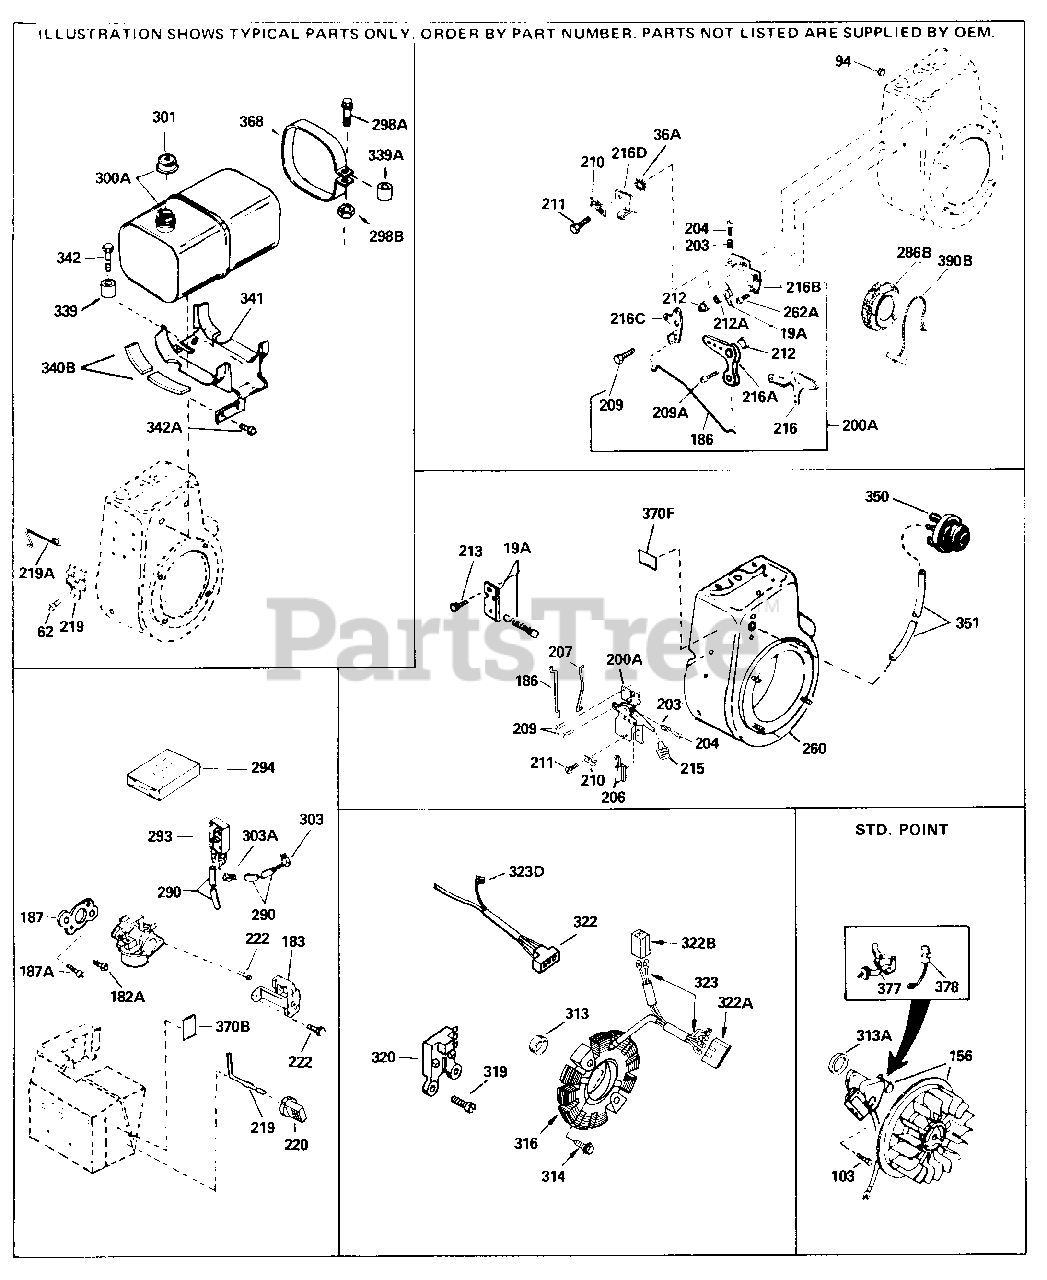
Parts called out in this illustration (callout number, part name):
94	Nut Lock, 10-32
103	Screw, Torx T-15, 10-24 x 1"
206	Terminal Assy. (Use as required)
207	Link, Governor-to-throttle
260	Blower Housing (For electric starter)
275C	Muffler (Optional quiet muffler)
277A	Screw, 5/16-18x2-3/4" Used with 276A
290	Fuel Line (8.62") req.)
290	Fuel Line (Braided 16")(41 cm) Use as req.
290	Fuel Line (Braided 32")(81 cm) Use as req.
301	Fuel Cap (Red 1-1/2" ID) (also availa ble in Packaged Part #740005B) (Red Plastic) (Spurt Resistant, Low Profil e) (1-3/16" I.D.)
301	Fuel Cap (Red Plastic) (Spurt Resista nt, High Profile) (1-3/16" I.D)
301	Fuel Cap (Red)
301	Fuel Cap (White Plastic)(Std) 1-1/2" I.D.
339	Spacer, Tank
341	Bracket, Fuel tank mounting
342	Screw, 1/4-20 x 5/8"
370B	Decal, Instruction Can be used on HM8 0 with stamped steel recoil starter.
370J	Decal, Instruction Can be used on HM8 0 with diecast starter.
408	Screen Seal Can be used on HM80 with stamped steel recoil starter
409	Spacer Can be used on HM80 with stamp ed steel recoil starter
410	Debris Screen Kit (Incl. 360, 370B, 3 87, 411 &413) (Can be used on HM80 wi th stamped steel recoil starter)
411	Debris Screen Can be used on HM80 wit h stamped steel recoil starter
413	Screw, 5/16-18 x 1-5/8" Can be used o n HM80 with stamped steel recoil star ter
425	Starter Muff Kit (Incl. 370J, 426 & 4 27) (Can be used on HM80 with di e cast starter)
429	Screw, 8-18 x 1-1/8" (3 Required) (Us e as required) (Refer to Mechanics Ha ndbook for installation instructions) .
430	Alternator, Add on (Use as required) (Refer to Mechanics Handbook for inst allation instructions).
431	Centering tube (Use with engines equi pped with die cast aluminum starter)( Use as required) (Refer to Mechanics Handbook for installation instruction s)
431	Centering tube (Use as required) (Ref er to Mechanics Handbook for installa tion instructions).
432	A.C. Lighting Connector (Use as requi red) (Refer to Mechanics Handbook for installation instructions).
432	D.C. Charging Connector (Use as requi red) (Refer to Mechanics Handbook for installation instructions).
433	Alternator Shaft (4.00") (Use with en gines equipped with cast aluminum sta rter)(Use as required) (Refer to Mech anics Handbook for installation instr uctions).
433	Alternator Shaft (Use with engines e quipped with stamped steel starter)(U se as required) (Refer to Mechanics H andbook for installation instructions ).
